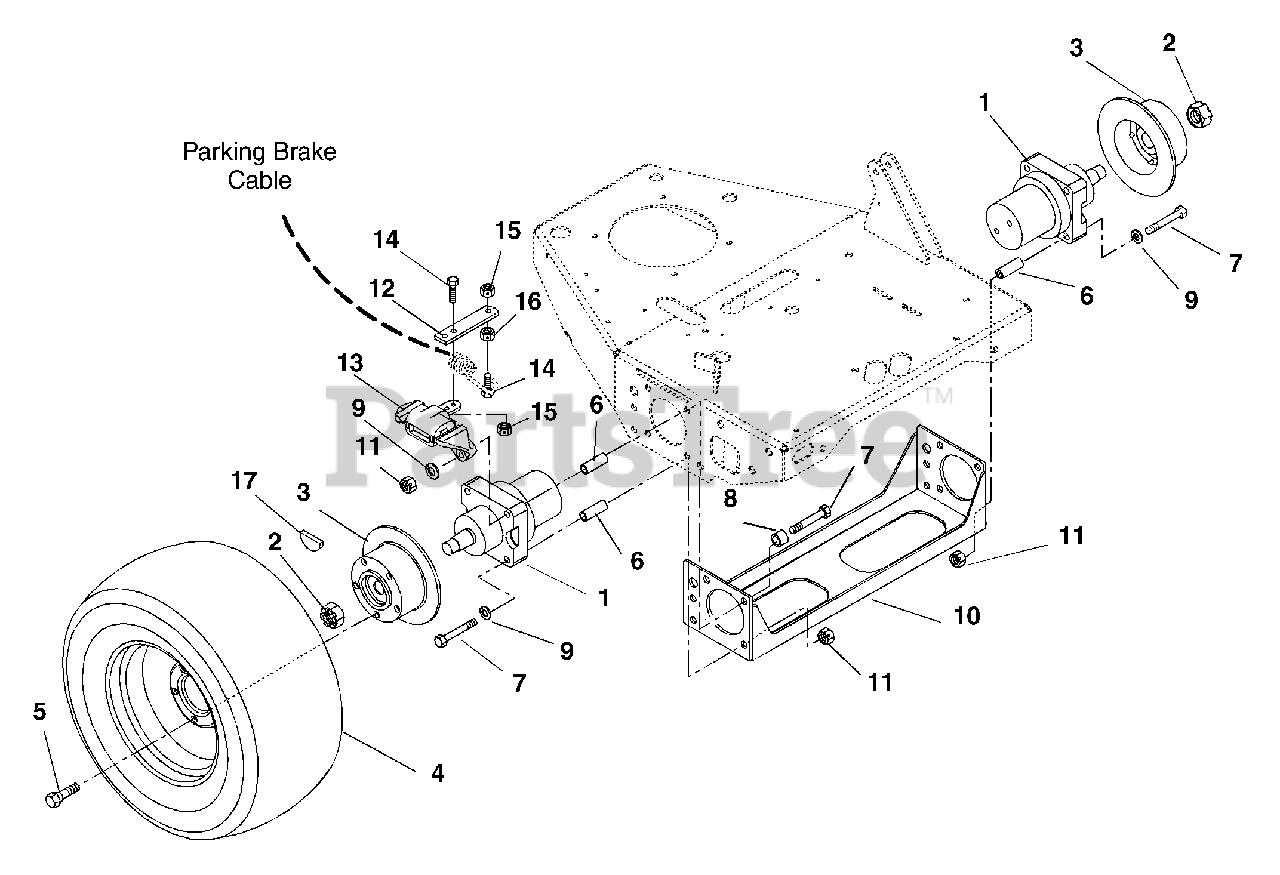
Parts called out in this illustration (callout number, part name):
1	Motor, Hydraulic Wheel
2	Nut, Locking-Jam-Patch 1.00-20
3	Hub and Disc
4	Wheel-Tire 23 x 10.50 - 12 Multi-Trac
5	Bolt-Lug .50-20 x 1.62
6	Bushing-Sleeve .513 x .748 x 2.129
7	Bolt-Hex .50-13 x 5.00 Grade 8
8	Spacer .50 x .75 x .32
9	Washer-Locking .50 x .125
10	Rod-Motor Connecting
11	Nut-Locking-Center .50-13
12	Arm, Extension Parking Brake
13	Caliper, Park Brake (Clockwise) Right Hand
13	Caliper,Park Brake (Counter Clockwise) Left Hand
14	Bolt-Hex .31-18 x 1.00 Grade 5
15	Nut-Locking-Nylon .31-18
16	Nut-Hex .31-18
17	Pad, Disk Brake
